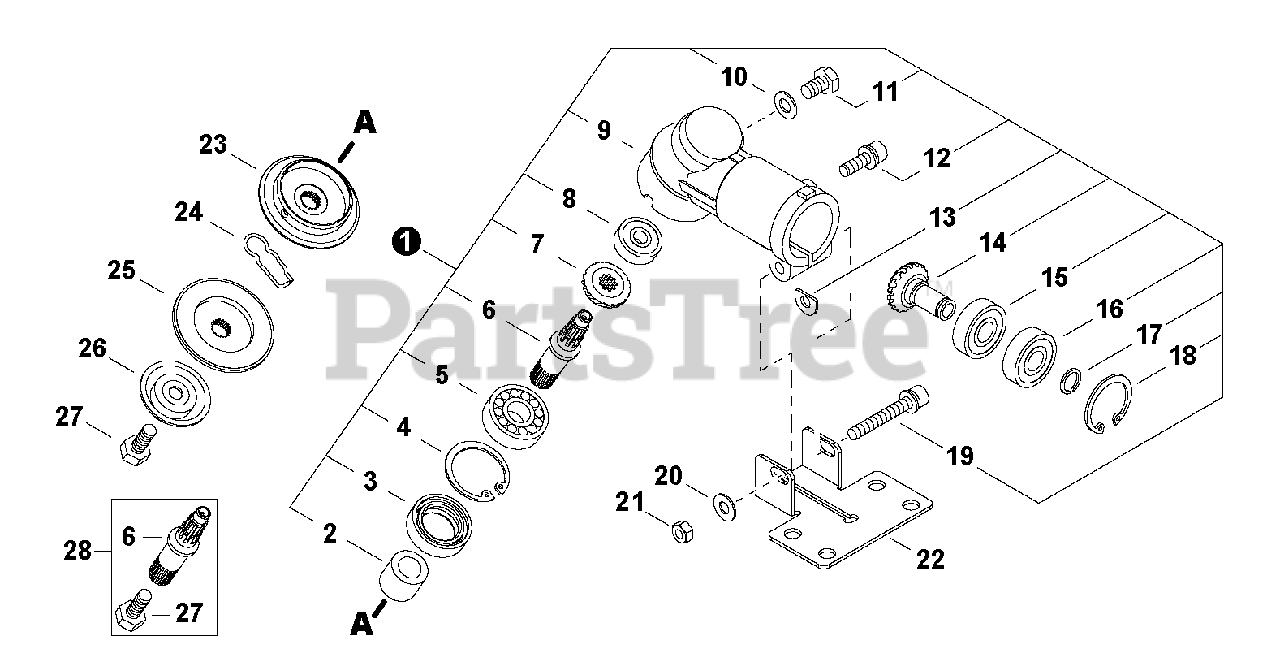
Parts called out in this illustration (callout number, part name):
1	Gear Case Assy
3	Seal, Oil
4	Ring, Snap dia.32
5	Bearing, Ball 6201
6	Shaft, Gear
7	Gear, Bevel
8	Bearing, Ball
9	Case, Gear
11	Bolt M6x10
12	Bolt M5x16
13	D-Washer
14	Gear, Pinion
15	Bearing, Ball 6901
16	Bearing, Ball 6901zz
17	Ring, Snap dia.12
18	Ring, Snap dia.24
19	Bolt M6x40
20	Washer 6
21	Nut, Hex M6
22	Plate, Shield Mounting
23	Holder (A)
24	Clip, Safety
25	Holder (B)
26	Guard, Bolt
28	Gear Shaft Set
